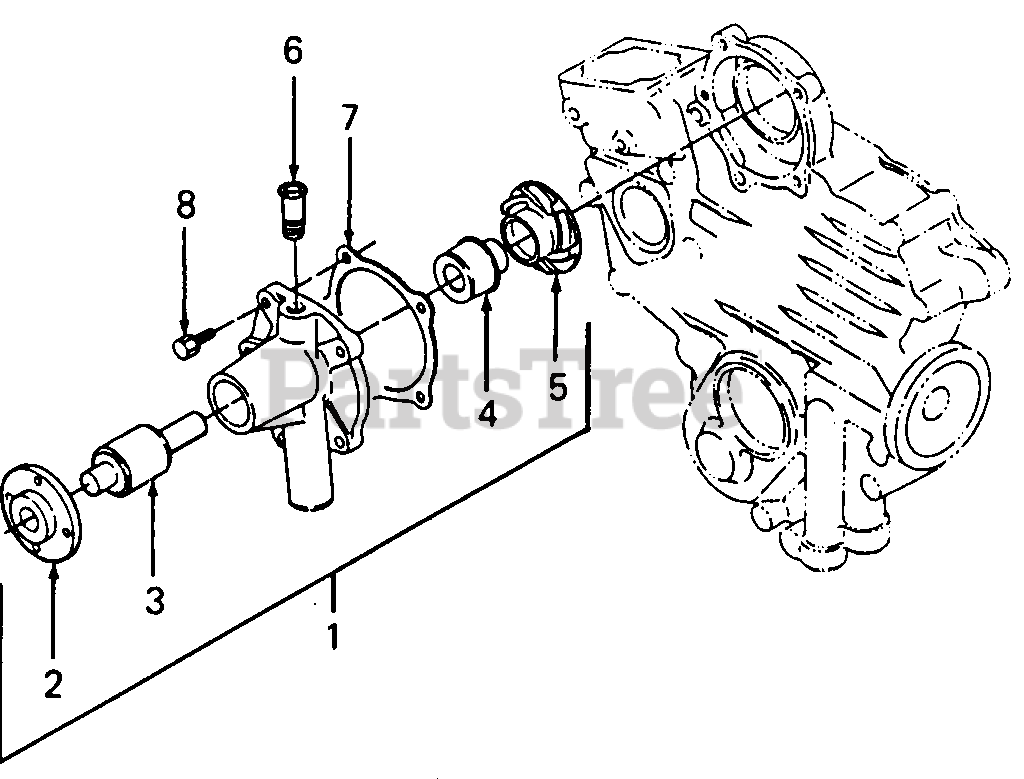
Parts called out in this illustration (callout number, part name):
1	Water Pump Assy
2	Flange, Water Pump
3	Bearing, Ball
4	Mechanical Seal Assy
5	Impeller, Water Pump
6	Pipe, Water Return #1
7	Gasket, Water Pump
